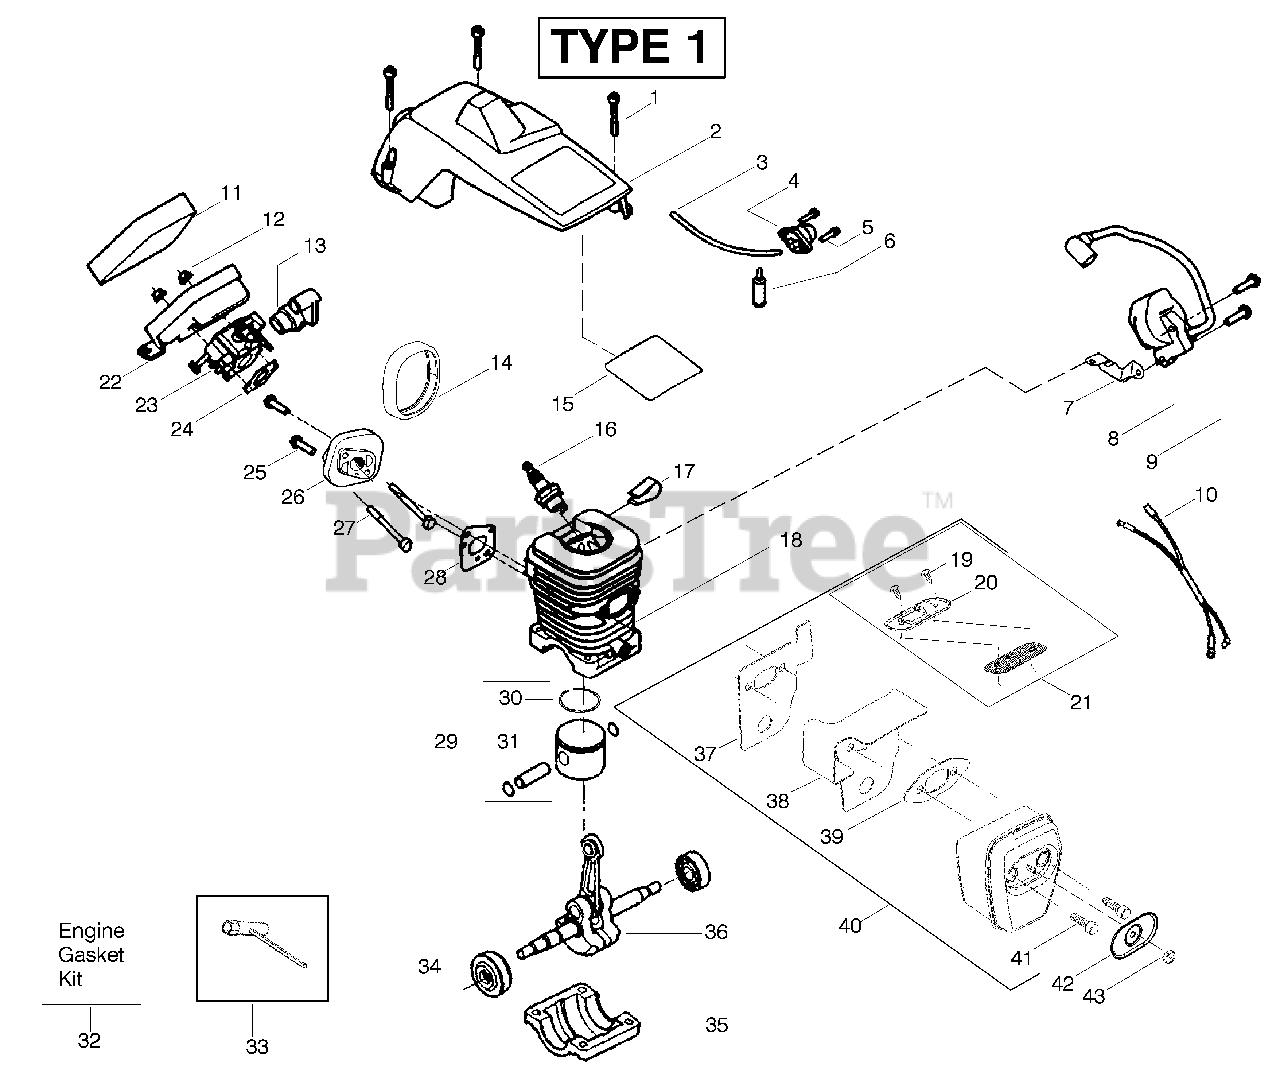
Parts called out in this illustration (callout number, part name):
2	Assy-Cylinder Shield
3	Kit-Fuel Line
4	Assy- Air Purge
6	Assy-Fuel Pick-Up
7	Strap-Ground
8	Ignition Module
10	Assy-Wire Harness
11	Foam- Air Filter
13	Grommet-Carb Adjust
14	Seal-Carb Adapter
15	Reflector-Heat
16	Spark Plug
17	Clip-High Tension Lead
18	Cylinder
19	Screw-Outlet Cover
20	Cover - Outlet
21	Kit-Spark Arrestor
22	Air Filter Housing
23	Kit-Carburetor (WT-600)
23	Kit-Carburetor (WT-637)
23	Kit-Carburetor (W-14-A)
24	Gasket-Carb.
26	Carb. Adapter
28	Gasket- Adaptor
29	Kit-Piston
30	Ring-Piston
31	Retainer-Piston Pin
32	Kit-Engine Gasket
33	Bar Wrench
34	Assy-Seal & Bearing
35	Cap-Crankcase
36	Assy-Crankshaft
37	Backplate
38	Guide-Outlet
39	Gasket-Muffler
40	Assy-Muffler
41	Bolt-Muffler
42	Cover-Bolt
43	Nut-Brass
